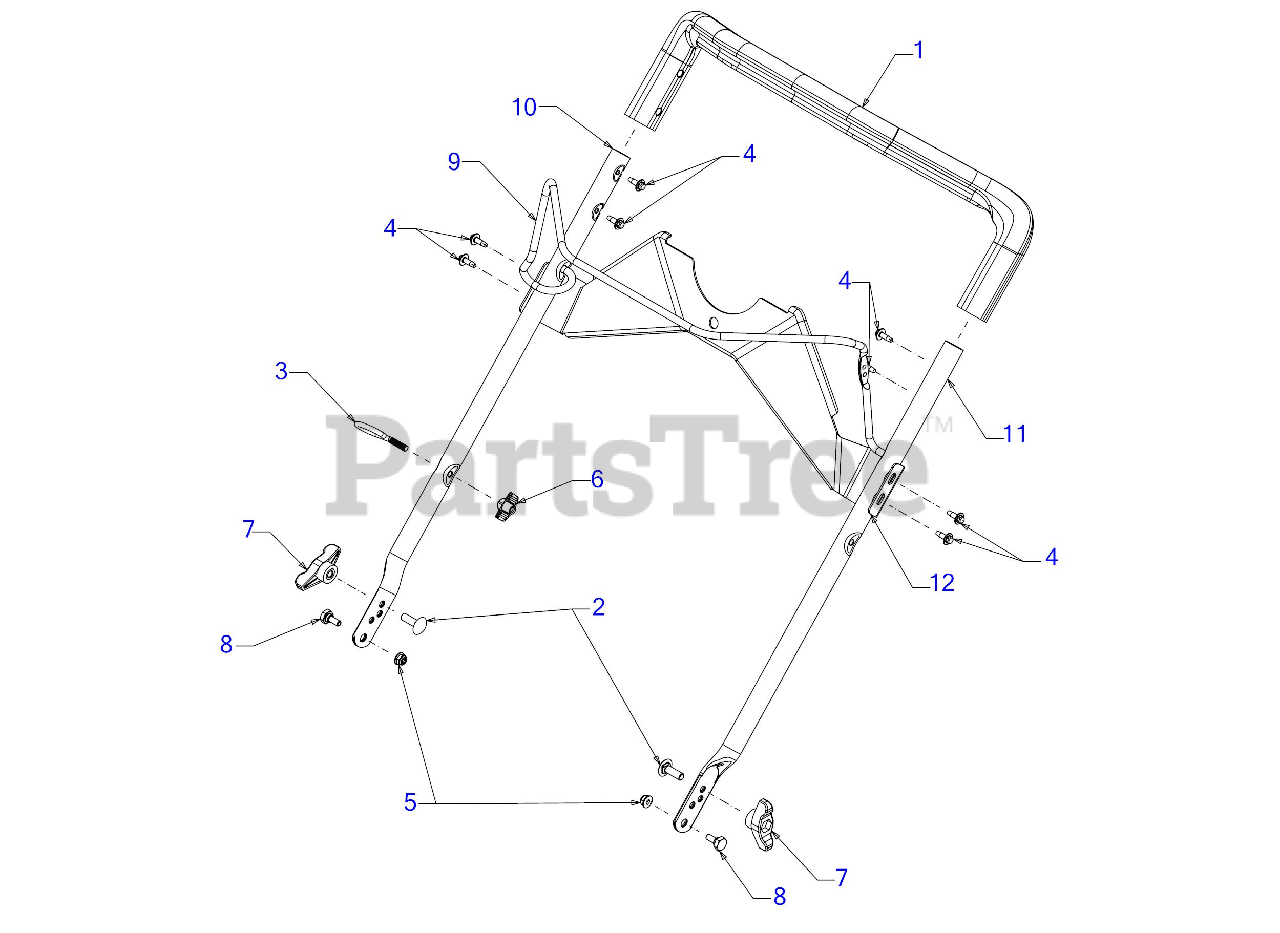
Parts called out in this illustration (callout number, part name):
1	HANDLE GRIP ASSEMBLY
2	SCREW 5/16-18 x 1.00 GR5
3	EYEBOLT 1/4-20
4	SCREW M6-1 x .625
5	FLANGE LOCK NUT
6	HANDLE KNOB
7	WING KNOB 5/16-18
8	SHOULDER SCREW
9	DRIVE BAIL
10	UPPER HANDLE (RH)
11	UPPER HANDLE (LH)
12	HANDLE PANEL
